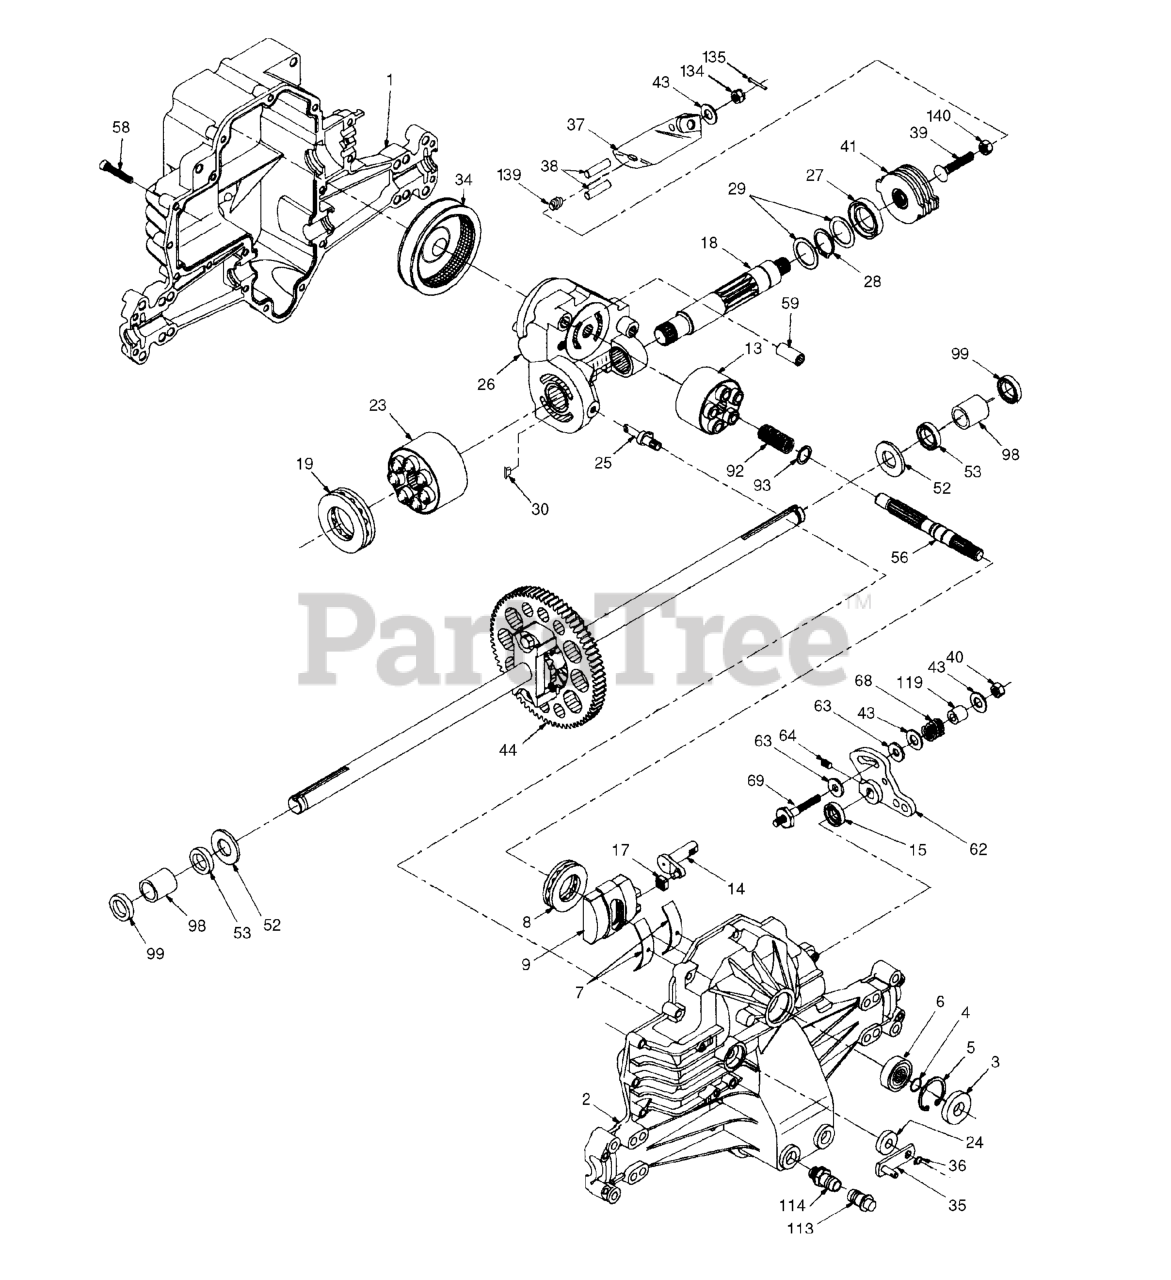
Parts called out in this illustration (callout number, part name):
1	HOUSING, LOWER
2	HOUSING.UPPER.70122.HYDRO-GEAR
3	SEAL.LIP.H-G.(9008000-0128)
4	RING RETAINING 2003016
5	RING.RETAINING.(2003052)
6	BALL BEARING
7	CRADLE BEARING
8	BEARING, THRUST 50551
9	SWASHPLATE (2003087)
13	BLOCK, CYL ASSY
14	TRUNNION ARM
17	SLOT GUIDE
18	SHAFT, MOTOR
19	BEARING, THRUST 50552
23	BLOCK, CYL ASSY
25	BYPASS ACTUATOR
26	CENTER SECTION ASS'Y KIT
28	RETAINING RING
34	ELEMENT, OIL FILTER
35	BYPASS ARM
36	RETAINING RING 44870
37	ACTUATING ARM
38	ACTUATING PIN 44891
39	BOLT 5/16-24 X 1-3/4
40	LOCKNUT, HEX 5/16-24
41	BRAKE ROTOR 70135 HYDRO-GEAR
43	WASHER .34X.88X.06.44130
44	DIFFERENTIAL ASSEMBLY
52	WASHER.HYDRO-GEAR 44875
53	SEAL.HYDRO.53901
56	SHAFT.INPUT.50005
58	BOLT #44876
62	CONTROL ARM 50254
63	DAMPENER PUCK
64	SCREW.SET.50018
68	SPRING HELICAL COMP 50277
69	STUD 5/16-24 50284
92	SPRING 2003014
98	BEARING SLV 50137
99	RP SEAL, WIPER
113	CAP, VENT ASSY
114	O-RING KIT 70110
119	SPACER.HYDRO GEAR 50278
134	NUT.CAS.HYD.44142
135	ID DOT HYDD
139	SPRING, COMPRESSION 50431
140	NUT, HEX 5/16-24
